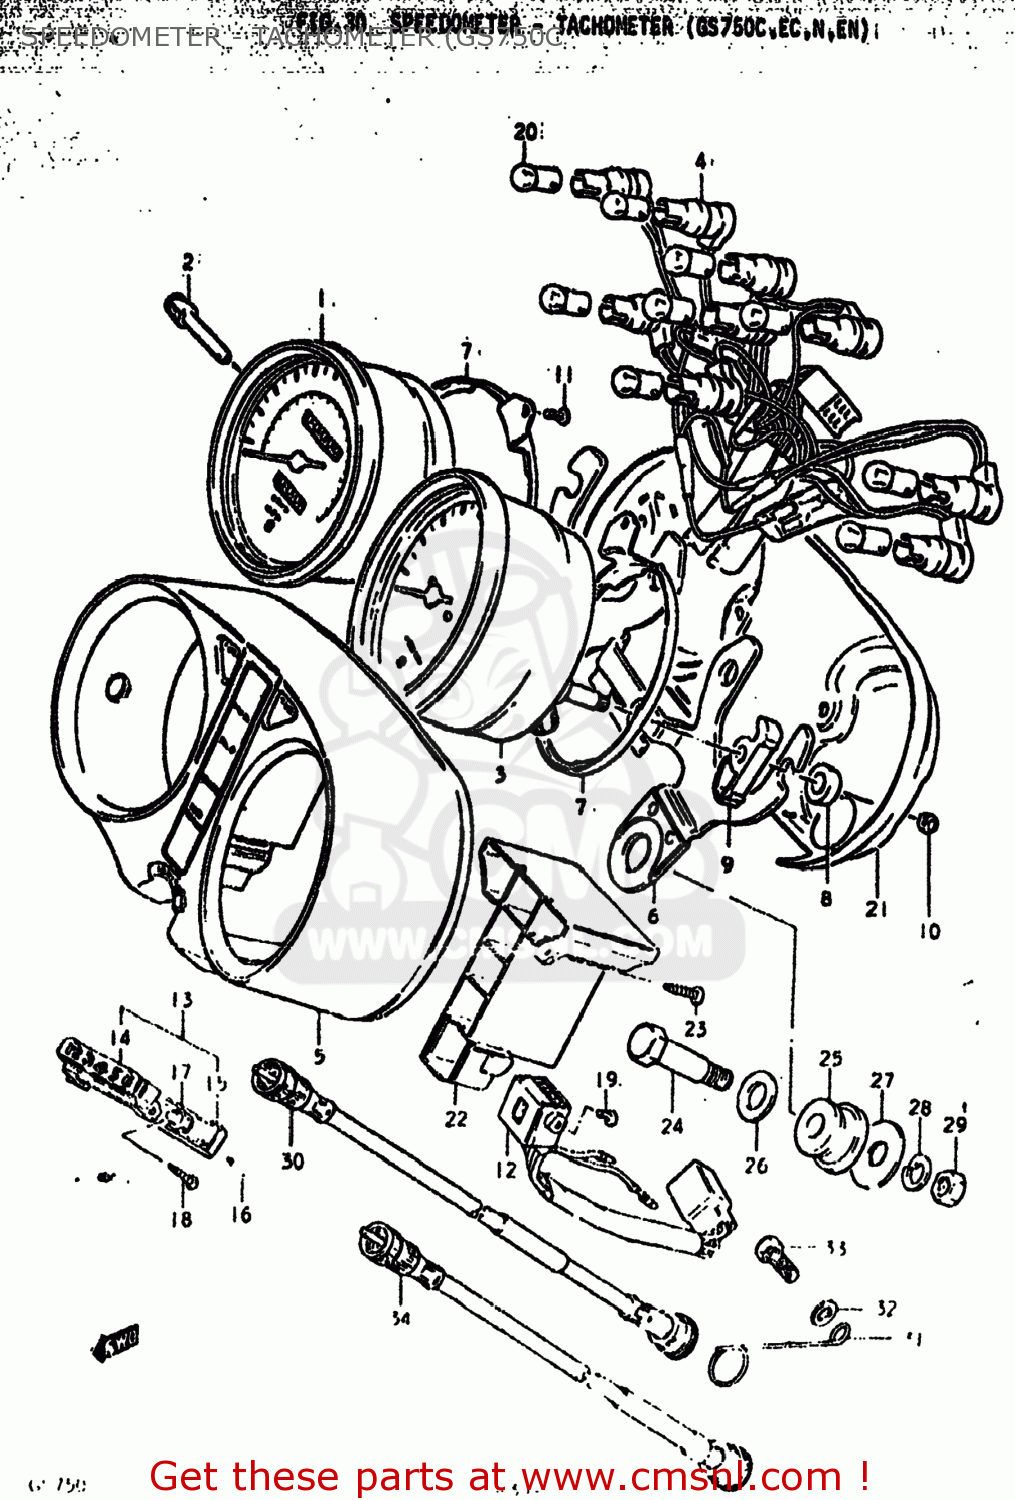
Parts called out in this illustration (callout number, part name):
0	SPEEDOMETER ASSEMBLY
1	SPEEDOMETER ASSEMBLY
2	KNOB
3	TACHOMETER
4	SOCKET,METER
5	CASE
6	BRACKET,COMBINATION METER
7	PLATE,METER,UNDER
8	CUSHION,METER (A)
9	CUSHION,METER (B)
10	NUT
11	SCREW
12	INDICATOR ASSEMBLY,GEAR POSITION
13	INDICATOR ASSEMBLY,GEAR POSITION
14	CASE,GEAR INDICATOR
15	COVER,LWR
16	SCREW,GEAR INDICATOR
17	BULB(14V1.12W)
18	SCREW
20	BULB(12V3.4W,STANLEY,A72A)
21	PLATE,UNDER
22	CASE,PILOT BULB
23	SCREW
24	BOLT(8X31)
25	CUSHION,METER
26	WASHER
27	WASHER (8.7X22X2)
28	LOCK WASHER
29	NUT
30	CABLE ASSEMBLY,SPEEDOMETER
31	GUIDE,SPEEDOMETER CABLE
32	WASHER 6MM
33	BOLT, UPPER
34	CABLE ASSEMBLY,TACHOMETER
